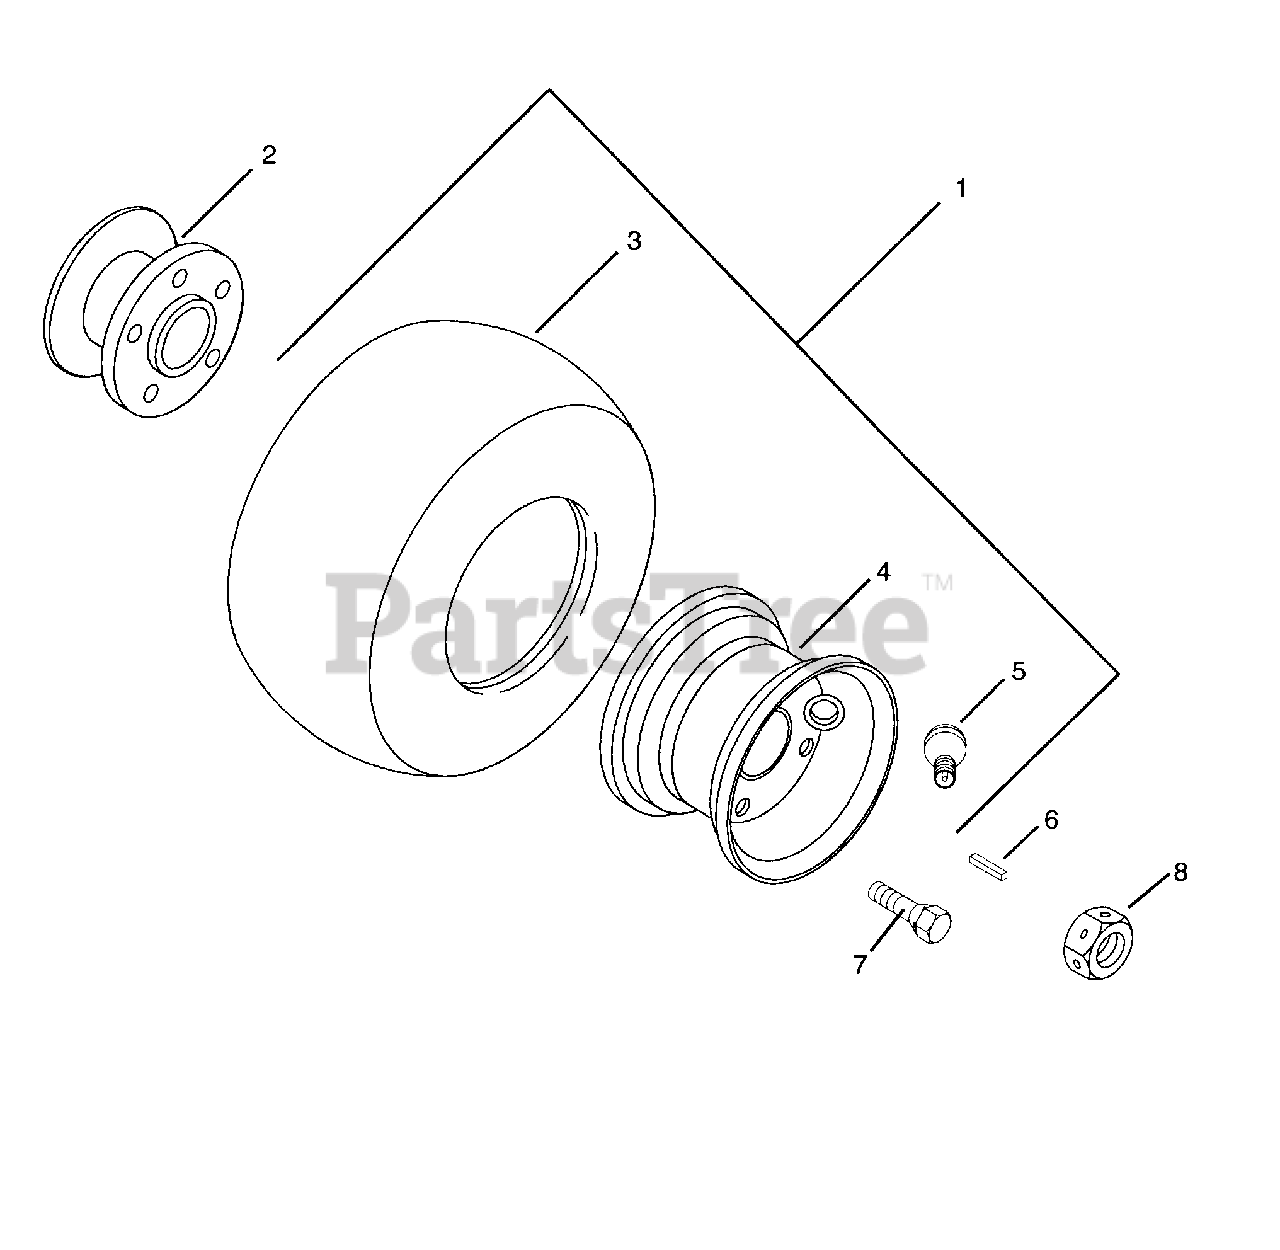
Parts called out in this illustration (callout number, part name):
1	Tire/Wheel Assembly 20 x 10-10
2	Hub-Disc Brake
3	Tire 20 x 10.00-10 Turf Trac RS
4	Wheel 10.00 x 7.75
5	Valve Stem Assembly
6	Key-Woodruff .156 x .625 x .25
7	Bolt-Lug .44-20 x 1.00
8	Nut-Pack 1.00-20
